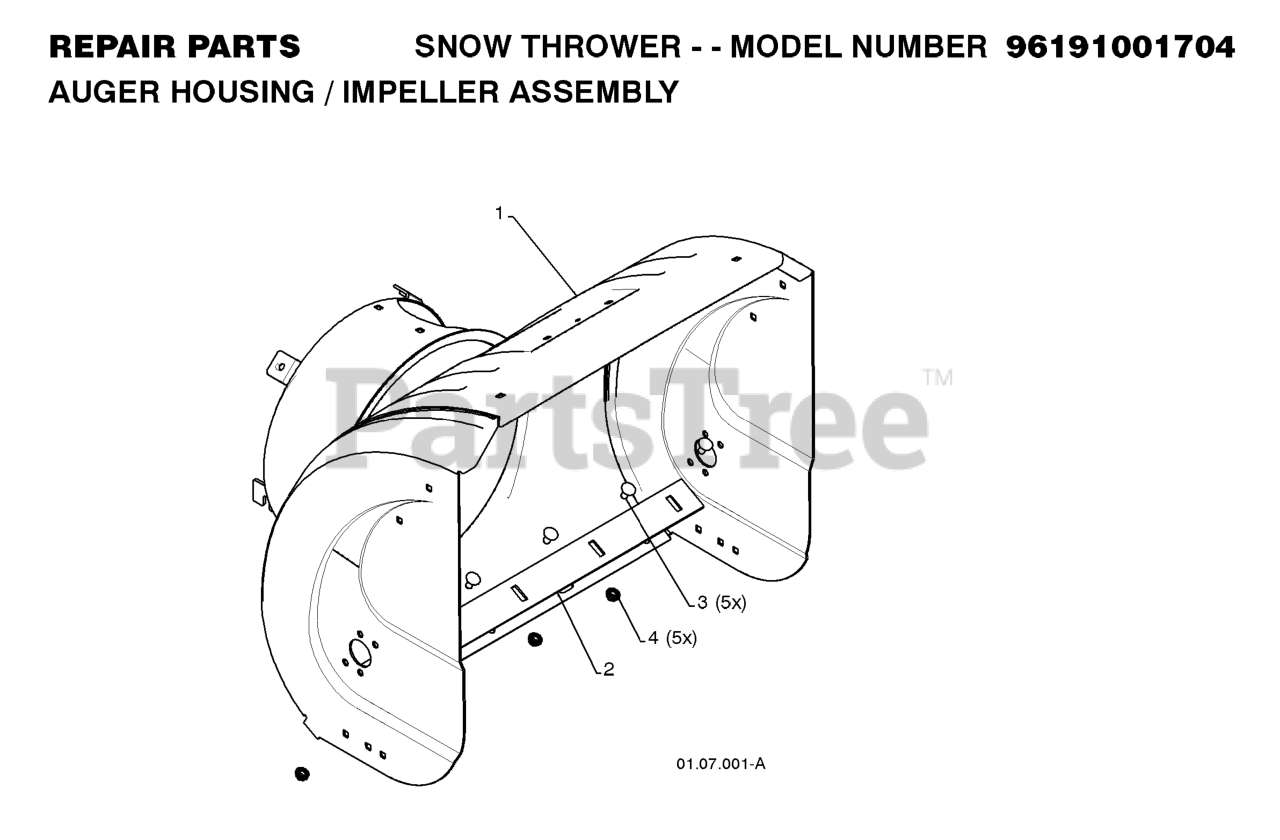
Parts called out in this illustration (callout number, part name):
1	AUGER HOUSING
2	BAR, SCRAPER
3	BOLT
4	NUT.FLANGE.5/16
